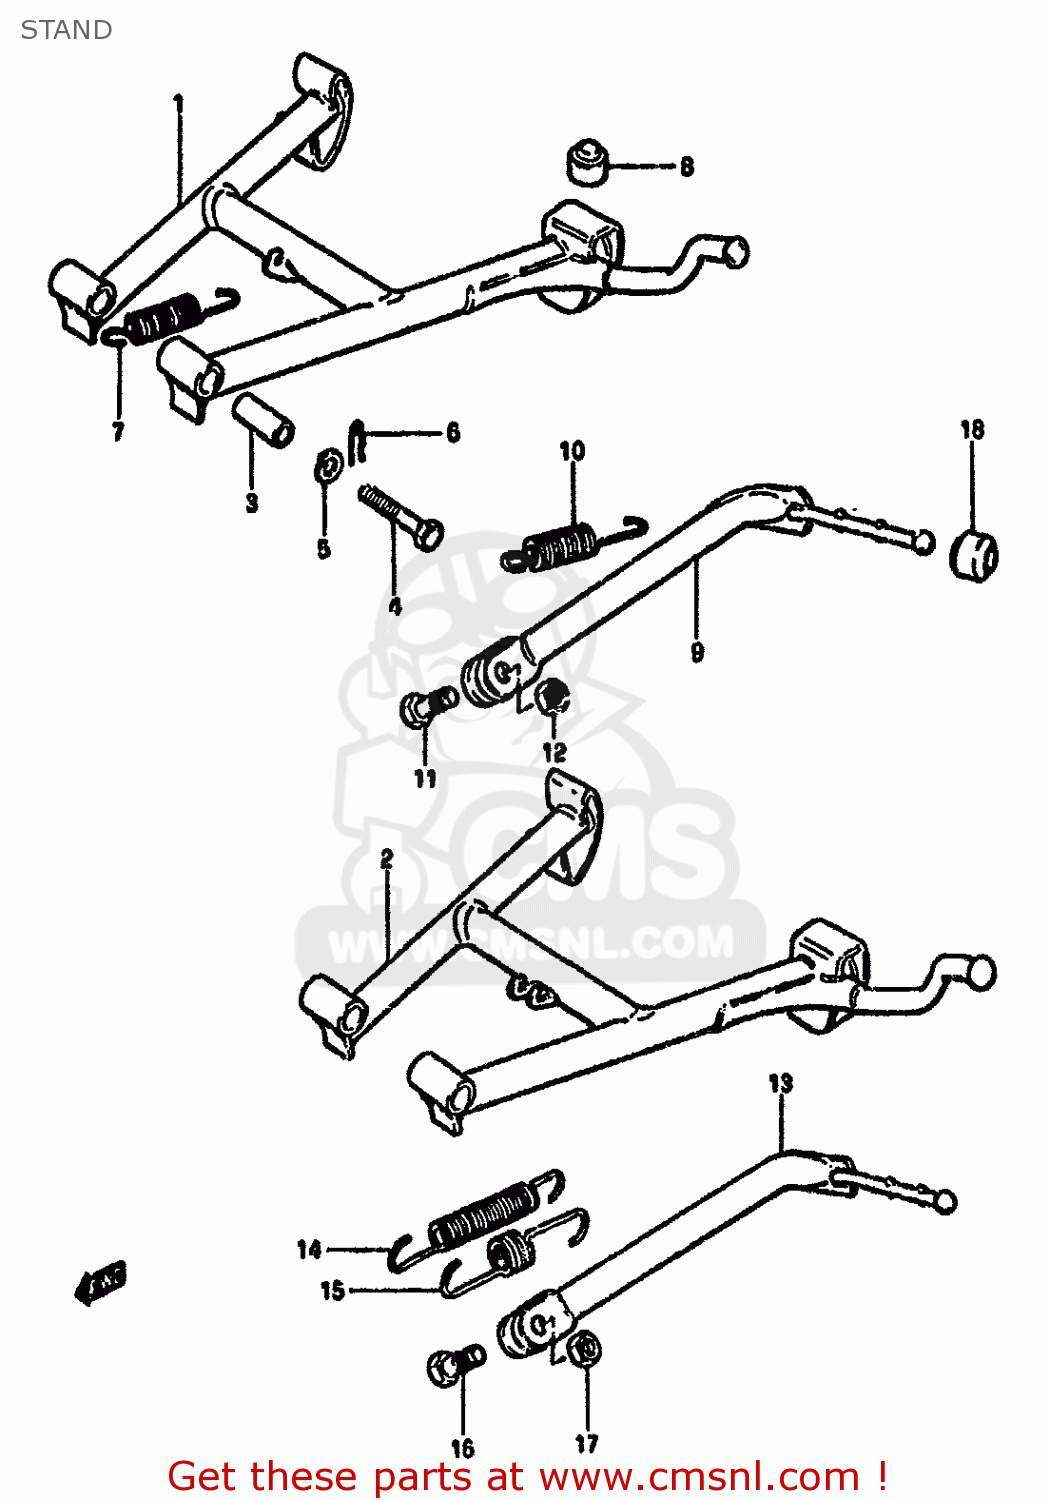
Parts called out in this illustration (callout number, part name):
1	STAND,CENTER
2	STAND,CENTER
3	SPACER(10X16X38.8)
4	BOLT
5	LOCK WASHER
6	CLIP
7	SPRING
8	CUSHION
9	STAND,SIDE
10	SPRING
11	BOLT(10X30)
12	NUT
13	STAND,PROP
14	SPRING
15	SPRING, OUTER
16	BOLT
17	NUT
18	CUSHION
